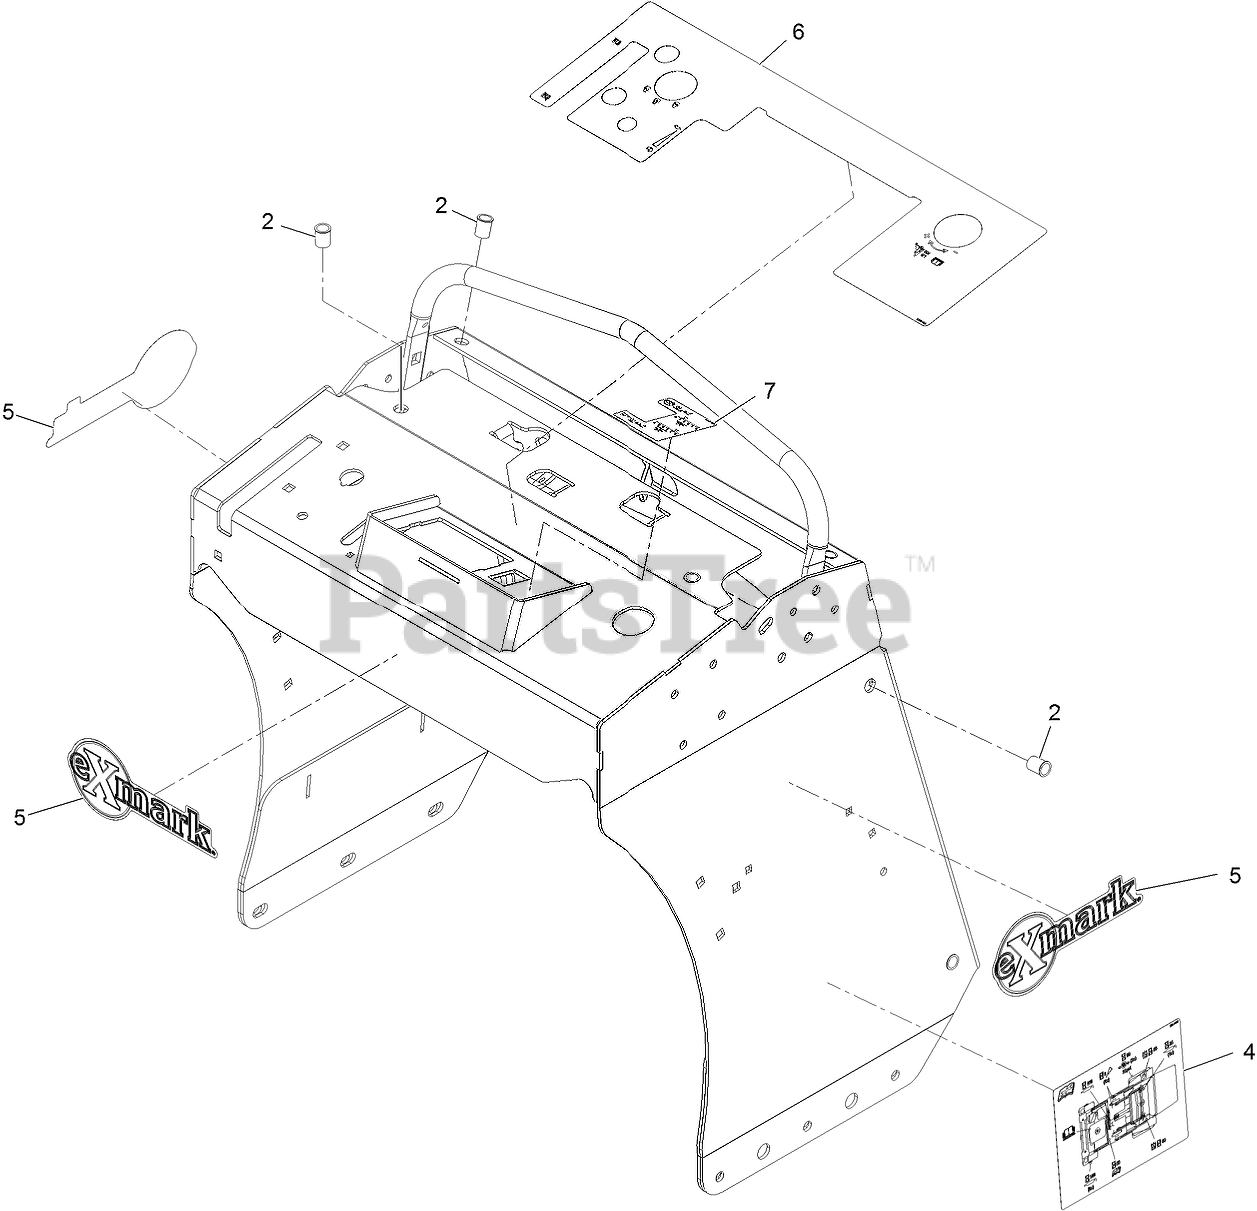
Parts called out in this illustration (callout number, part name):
2	NUT-CLINCH
4	DECAL-AID, SERVICE
5	DECAL, EXMARK LOGO
6	DECAL-PANEL, CONTROL
7	DECAL-CONTROL, TINE
